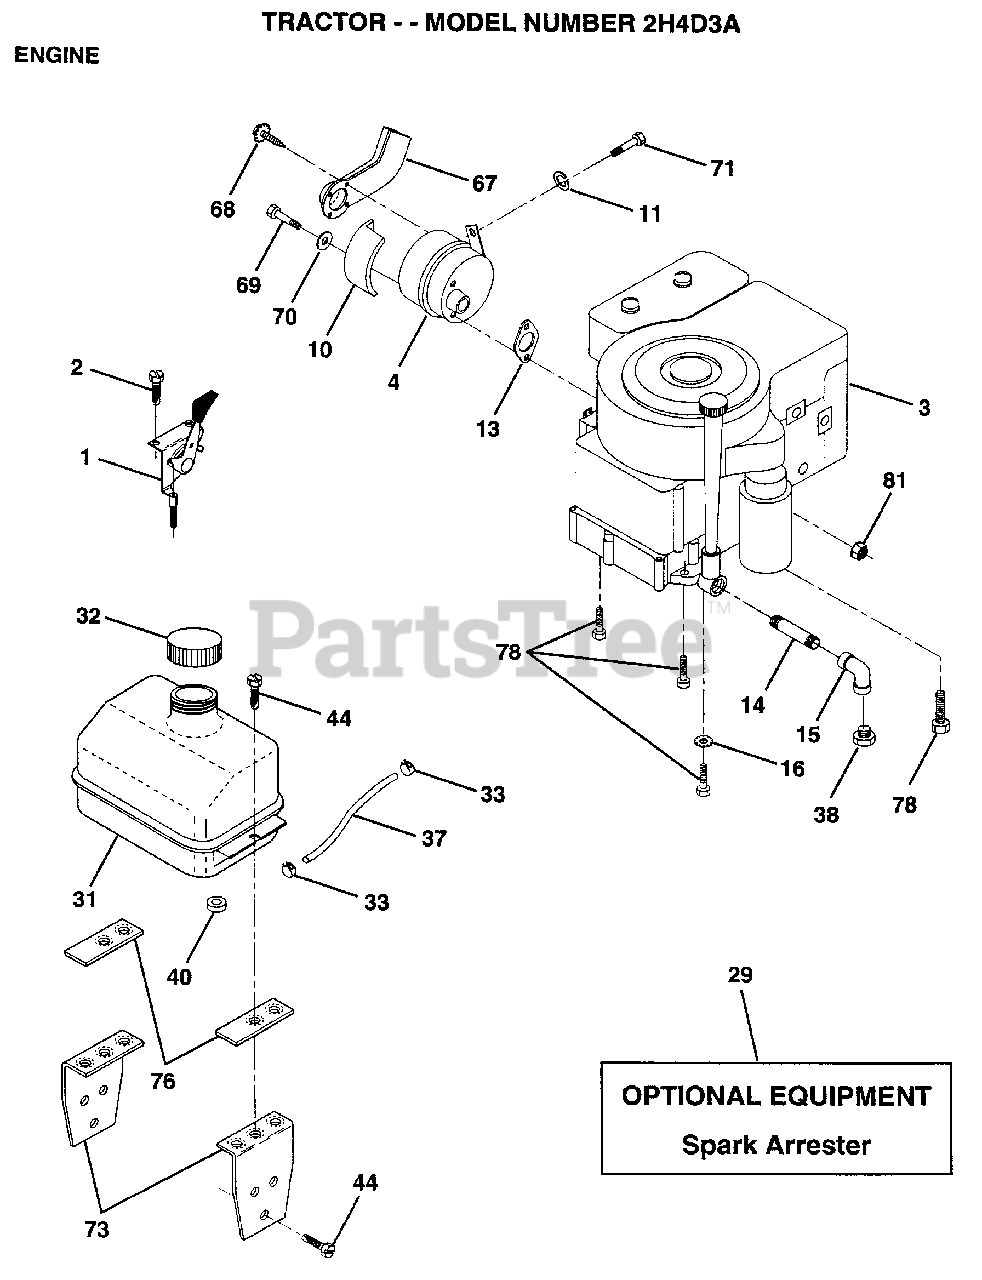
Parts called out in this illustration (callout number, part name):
1	THROTTLE CONTROL
2	SCREW LT
4	MUFFLER LTV
10	SHIELD HEAT LTV
14	PIPE NIPPLE
15	ELBOW
16	LOCKWASHER
31	TANK.FUEL.LT.
32	CAP ASM FUEL
33	HOSE CLAMP
37	LINE FUEL
44	SCREW HEX CRT
46	WASHER
67	DEFLECTOR MUFFLER
69	"BOLT,HEX"
70	WASHER T
73	"CLAMP,FUEL TANK T"
76	BRKT FUEL TANK T
78	SCREW
81	NUT
